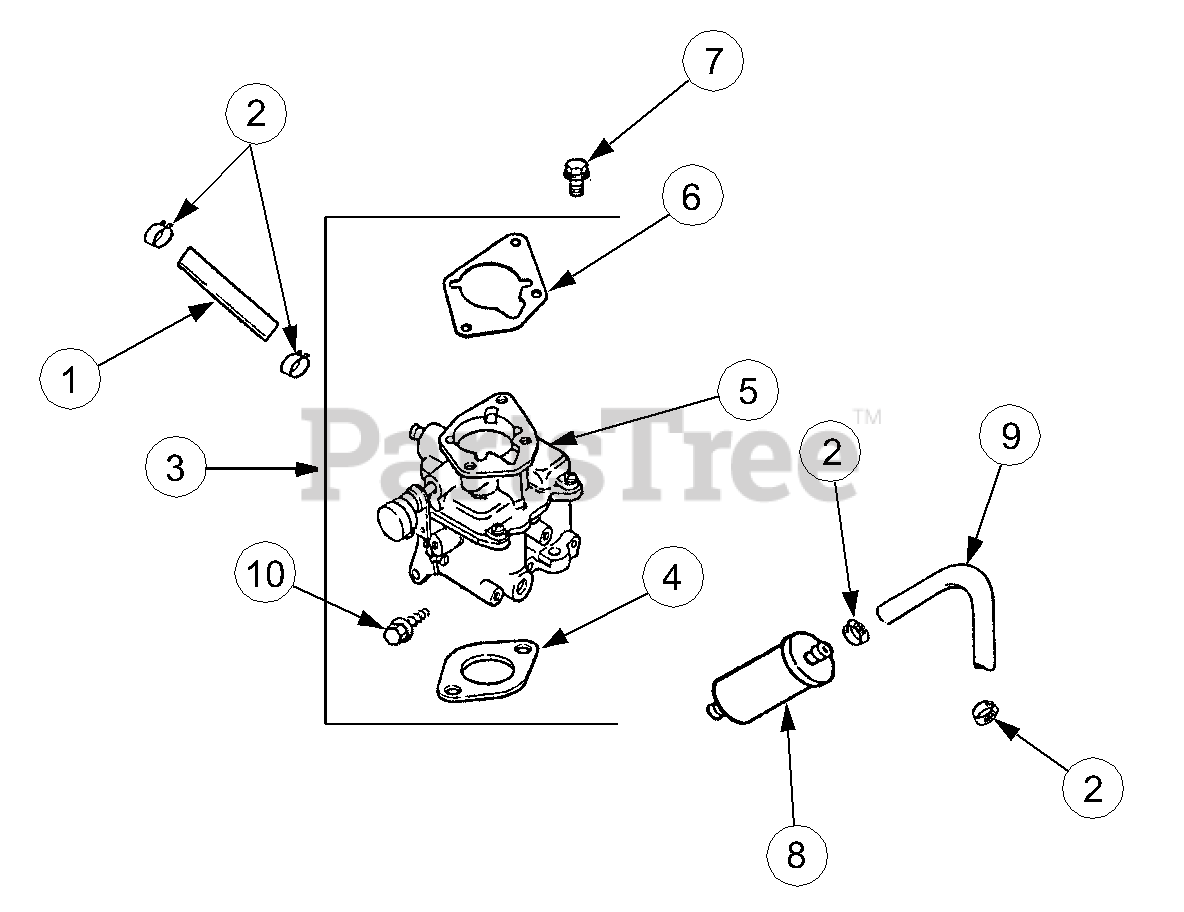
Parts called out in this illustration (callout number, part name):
1	Line, Fuel 10"
2	Clamp, Hose
3	Kit, Carburetor w/Gasket
4	Gasket, Carburetor
5	Carburetor Assembly
6	Gasket, Air Cleaner Base
7	Screw, Hex Flange
8	Filter, Fuel
9	Line, Fuel 11"
10	Screw, Throttle Stop
